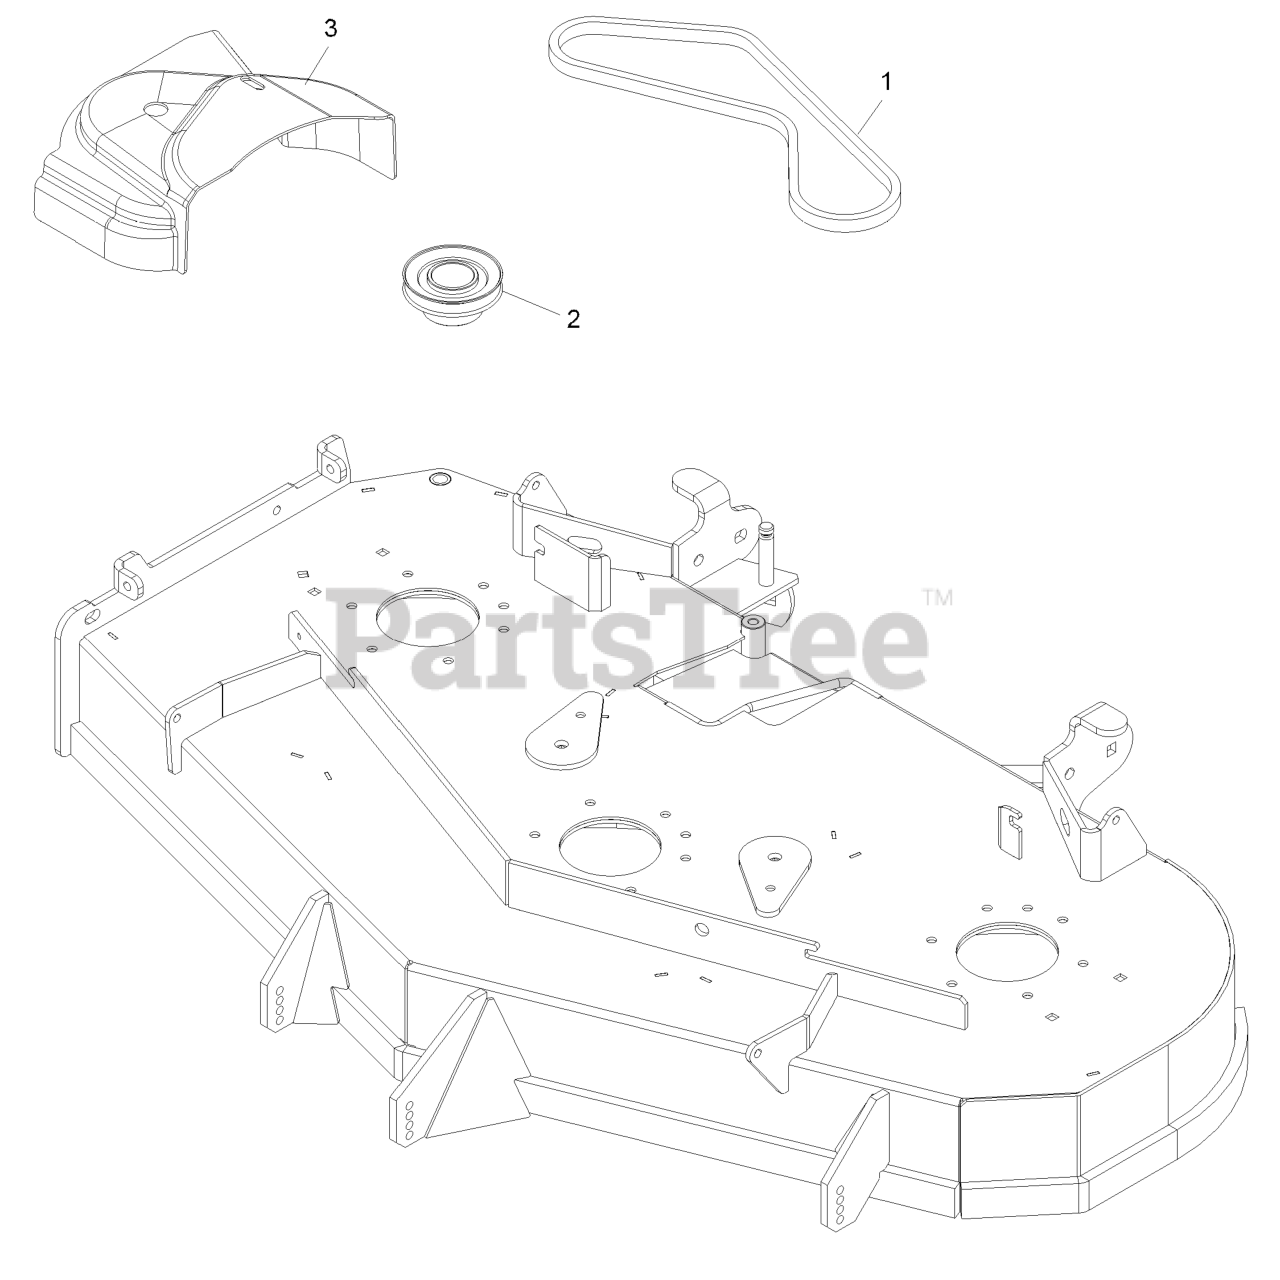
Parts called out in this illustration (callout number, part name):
1	BELT, BLOWER 52"DECK
2	SHEAVE,DRIVE LZUV 526
3	COVER,BELT UV 52
